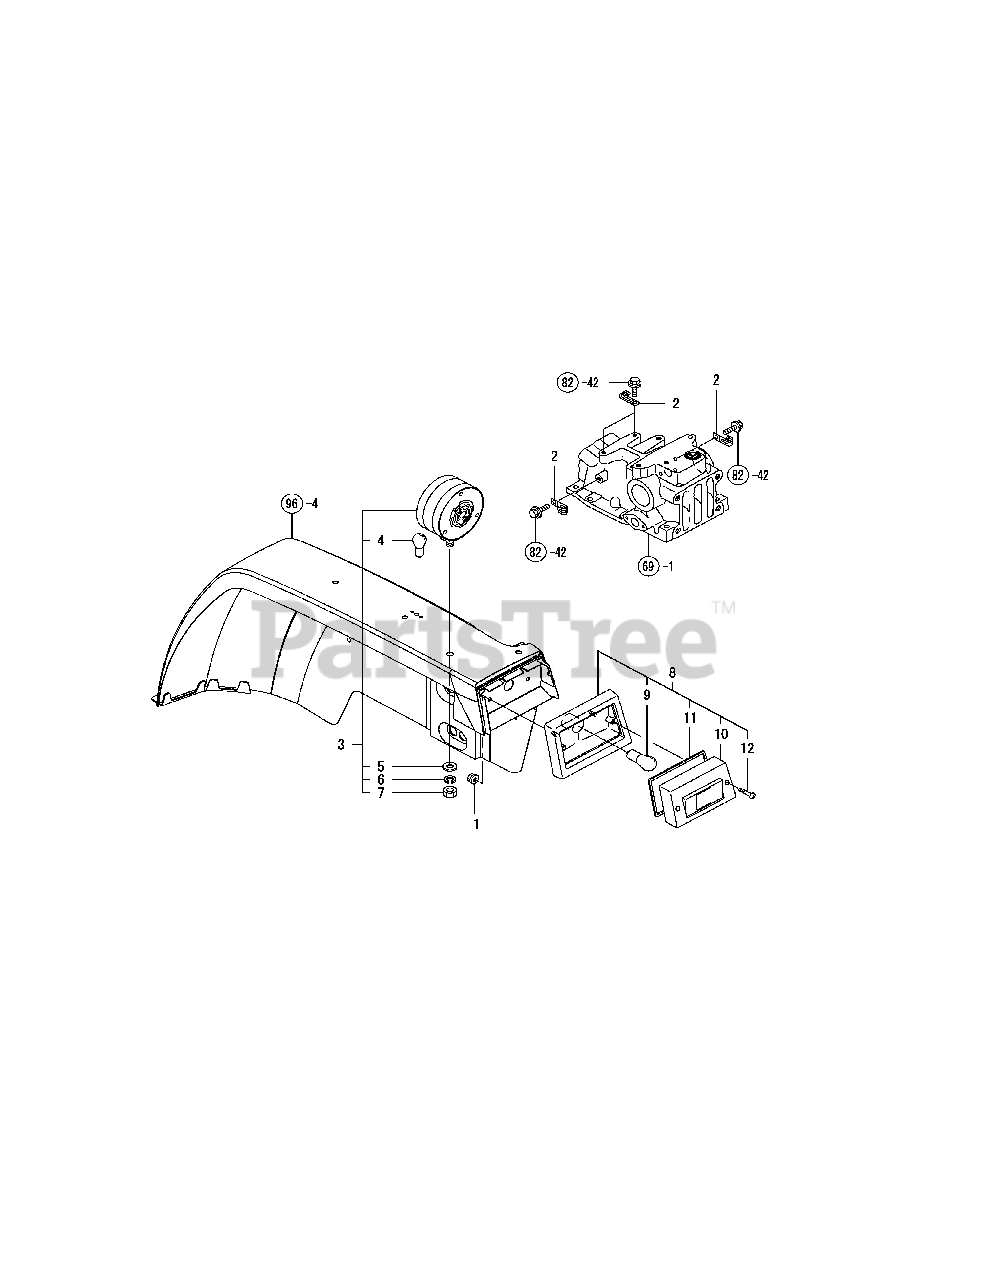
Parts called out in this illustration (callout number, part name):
1	NUT W/WASHER 6
2	CLAMP, WIRE HARNESS
3	LAMP KIT, WARNING
5	WASHER 12,POLISHED
6	SPRING WASHER 12
7	LOCK NUT M12 PLATED
9	BULB 12V-21/5W
